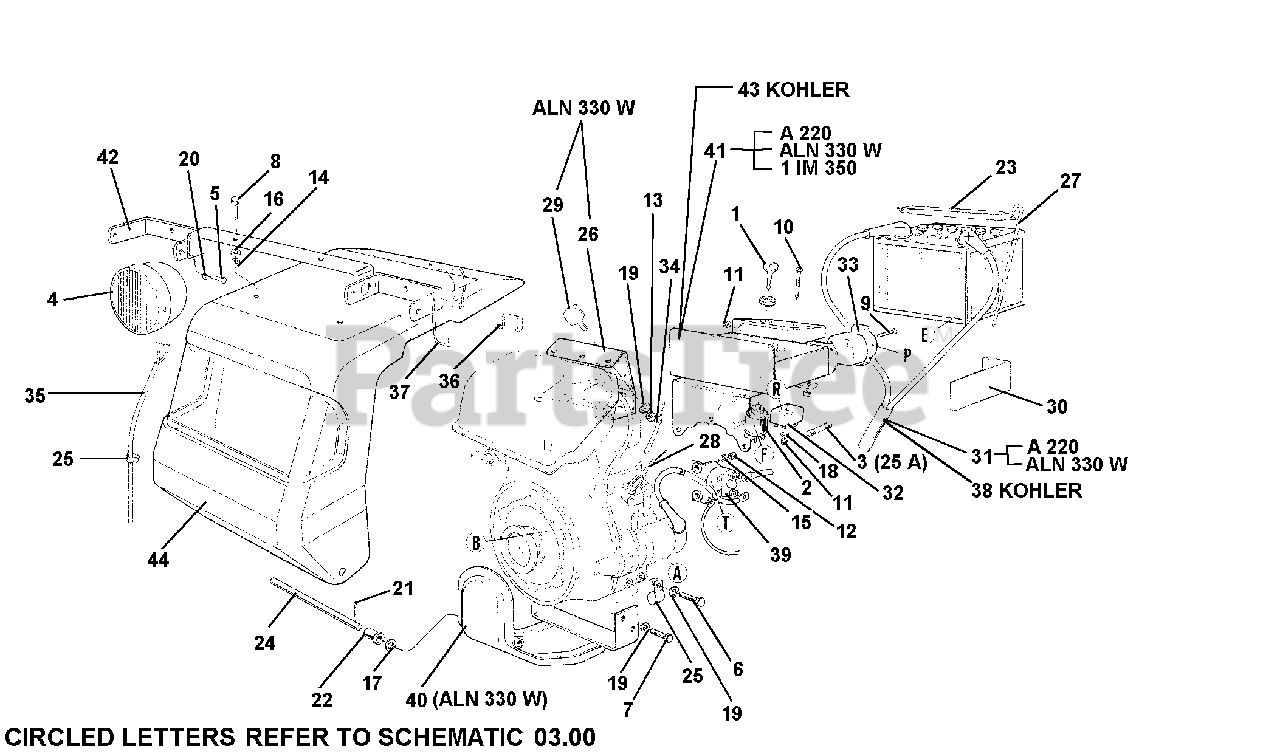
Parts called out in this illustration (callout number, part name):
3	FUSE 6 X 25 25A
5	SCREW TE M6 X 14
6	SCREW TE M8 X 12
7	SCREW M8 X 16
8	SCREW M8 X 25
9	SCREW TCCEI M4 X 30
10	SCREW TC M4 X 30 UNI 6107
14	NUT, SELF LOCKING M8
15	WASHER, FLAT 6.4
16	FLAT WASHER 9 X 24 UNI 6593
17	FLAT WASHER 10.5 X 21
18	LOCK WASHER B 4.3
19	WASHER, LOCK 8.4
20	WASHER, LOCK AZ 6.4 DIN 6798
21	PIN, COTTER A 3 X 20 UNI 1336
23	BATTERY BRACKET
24	PIN, COUPLING
25	CLAMP ENGINE
26	CONNECT. UPPER ELECTRIC ST.
27	BATTERY TIEROD
28	CABLE & SHEATH, ACCEL.LOMBAR
30	ANTISHOCK BAT
31	ELECTRIC START CABLES MC 715
33	7-POLE SOCKET
34	SHEATH CABLE
35	COVER CABLES
36	ELECTRIC STARTER HOOK
38	BATTERY CABLES
39	BOSCH RELAY 0332002160
40	HOOD LOWER COUPLING
41	SUPPORT BATTERY
42	LIGHT SUPPORT
43	KOHLER BATTERY SUPPORT
